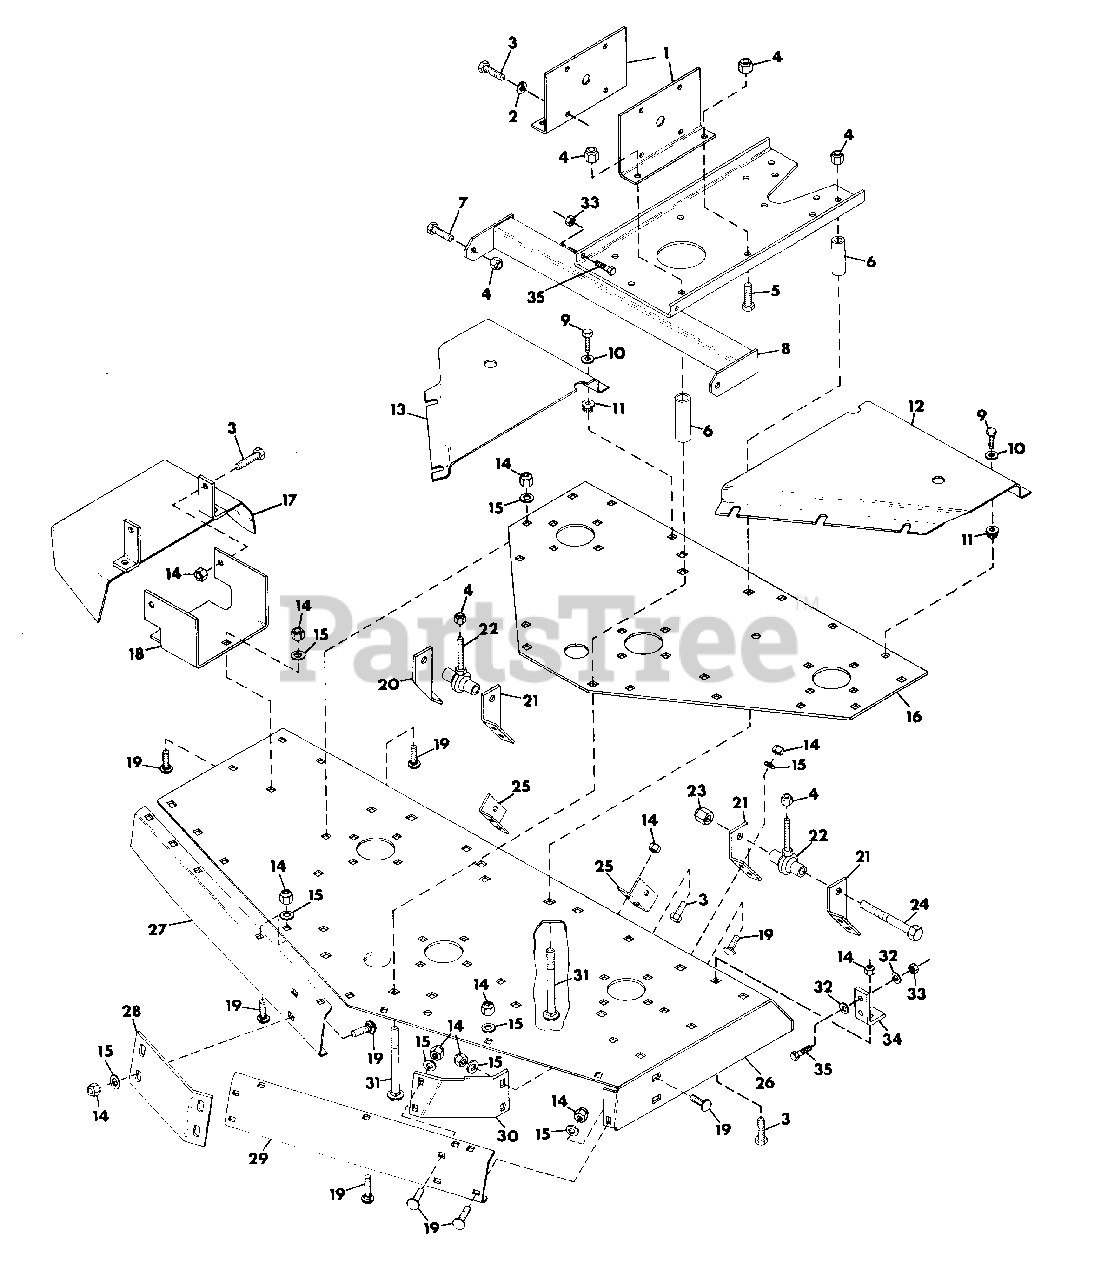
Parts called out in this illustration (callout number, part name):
1	PLATE, GEARBOX SUPPORT
2	WASHER, LOCK 3/8 REG.
3	BOLT, HEX 3/8-16X1.00
4	NUT, LOCK 1/2-13
5	BOLT, HEX 1/2-13X1.25
6	SPACER, .850X.546X2.18
7	BOLT, HEX 1/2-13X2.00
8	WELDMENT, SUPPORT PLATE
9	BOLT, HEX 1/4-20X.625
10	WASHER, FLAT .281X.625X.065
11	GROMMET, PLASTIC
12	COVER, BELT L.H.
13	COVER, BELT R.H.
14	NUT, LOCK 3/8-16
15	WASHER, FLAT .406X.812X.065
16	PLATE, DECK SUPPORT
17	WELDMENT, DISCHARGE CHUTE
18	BRACKET, DISCHARGE
19	BOLT, 3/8-16X1.00 RD HD SQ NK
20	PLATE, REAR ADJUSTMENT
21	PLATE, REAR ADJUSTMENT
22	ROD, END
23	NUT, LOCK 3/4-10
24	BOLT, HEX 3/4-10X3.50
25	BRACKET, LIFT
26	WELDMENT, 60" OFC
27	PLATE, FRONT COVER
28	BRACKET, FRONT DECK
29	PLATE, FRONT COVER L.H.
30	BAFFLE, FRONT
31	BOLT, 1/2-13X3.75 RD HD SQ NK
32	WASHER, FLAT .344X.688X.065
33	NUT, JAM 5/16-18
34	BRACKET, LIFT PIVOT
35	BOLT, 5/16-18X1.25
NS	DECAL, DANGER HAND
NS	DECAL, DANGER FOOT
NS	DECAL, WARNING EYE
NS	DECAL, AMERICA
NS	DECALS, PRO MASTER-60 MOWER
NS	STRIPE
